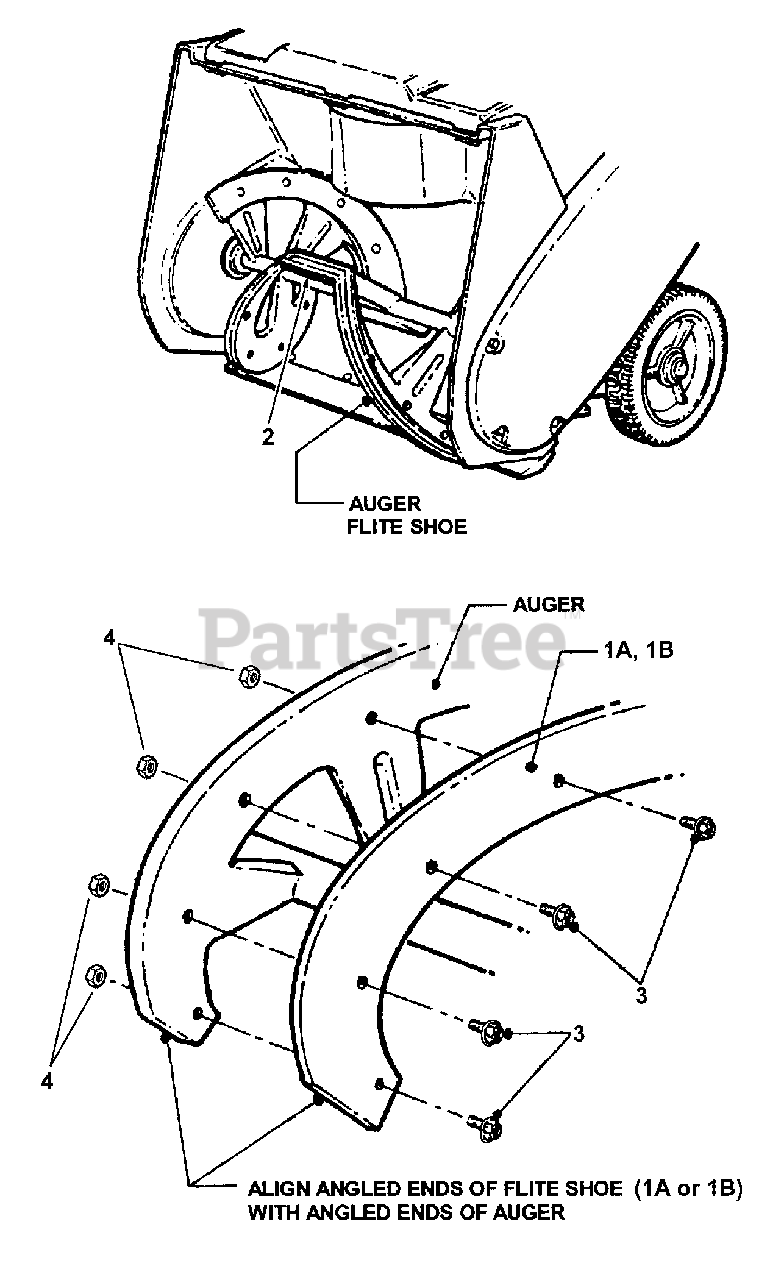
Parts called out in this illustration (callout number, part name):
1A	SHOE, 17" Flite Auger
1B	SHOE, 19" Flite Auger
2	SHOE, Flite Center
3	* SCREW, 1/4-20 x 1/2" Machine
4	* NUT, 1/4-20 Hex Center Lock, GR 5 or B
